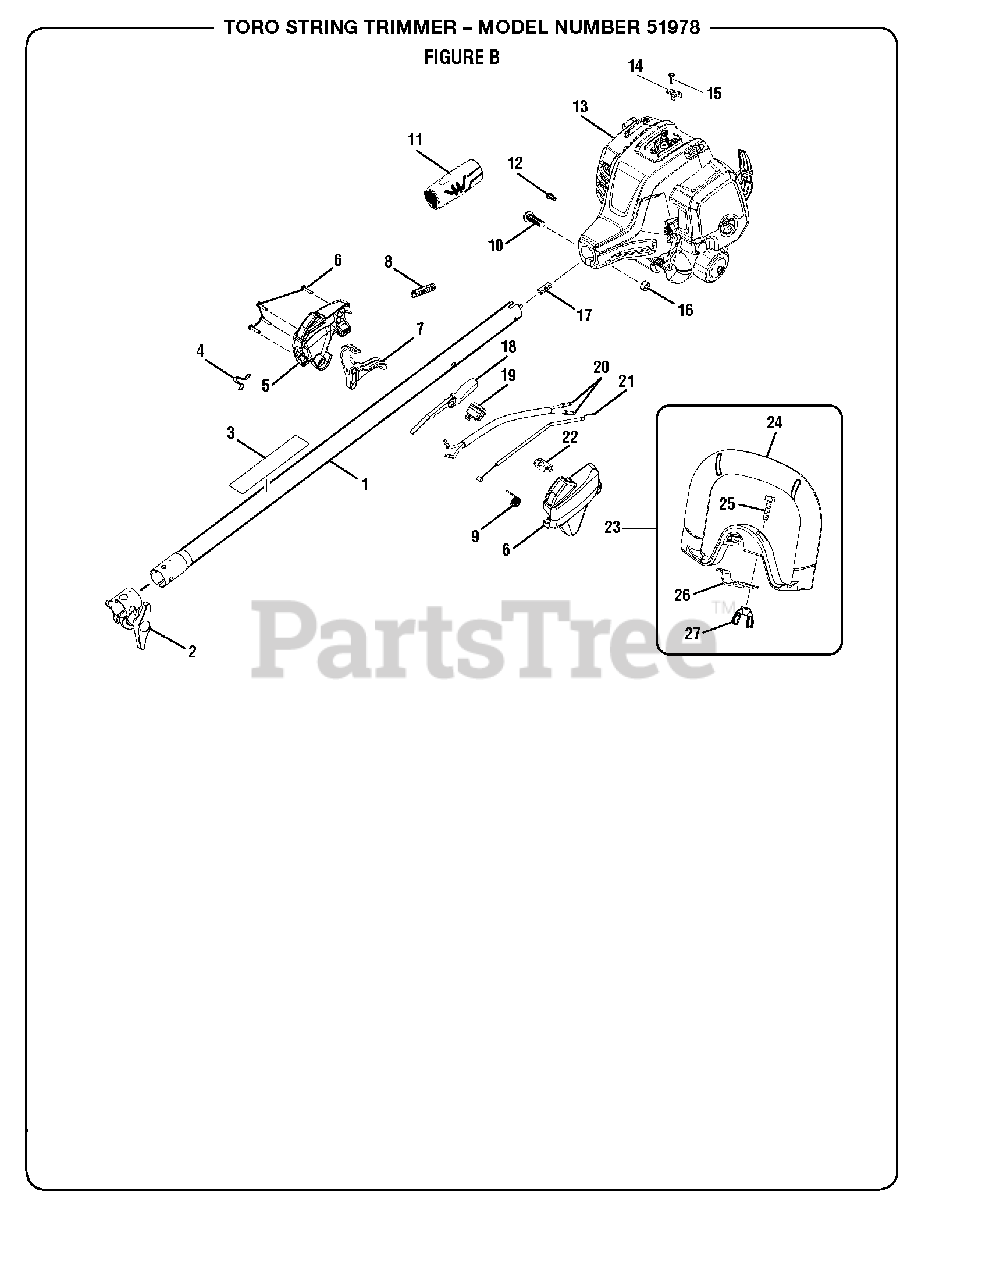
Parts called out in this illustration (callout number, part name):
1	Upper Boom Assembly
2	Boom Clamp Assembly
3	Warning Label
4	Shoulder Strap Clip
5	Control Handle Assembly
6	Screw (M4 x 20 mm, T20 Torx Hd.)
8	Corrugated Tube
9	Throttle Cable Spring
10	Screw (M6 x 30 mm)
11	Rear Handle Grip
12	Screw (M4 x 8 mm, T20 Torx Hd.)
13	Powerhead Assembly
14	Throttle Cable Clamp
15	Screw (M4 x 16 mm)
16	Hex Nut (M6.3 x 1)
17	Compression Spring
18	Trigger Lock
19	On/Stop Switch
20	Lead Assembly
21	Throttle Cable
22	On/Stop Label
23	Front Handle Assembly
24	Front Handle w/Grip
25	Screw (1/4-20 x 1 in., Sq. Hd.)
26	Front Handle Clamp
27	Wing Nut (1/4-20)
